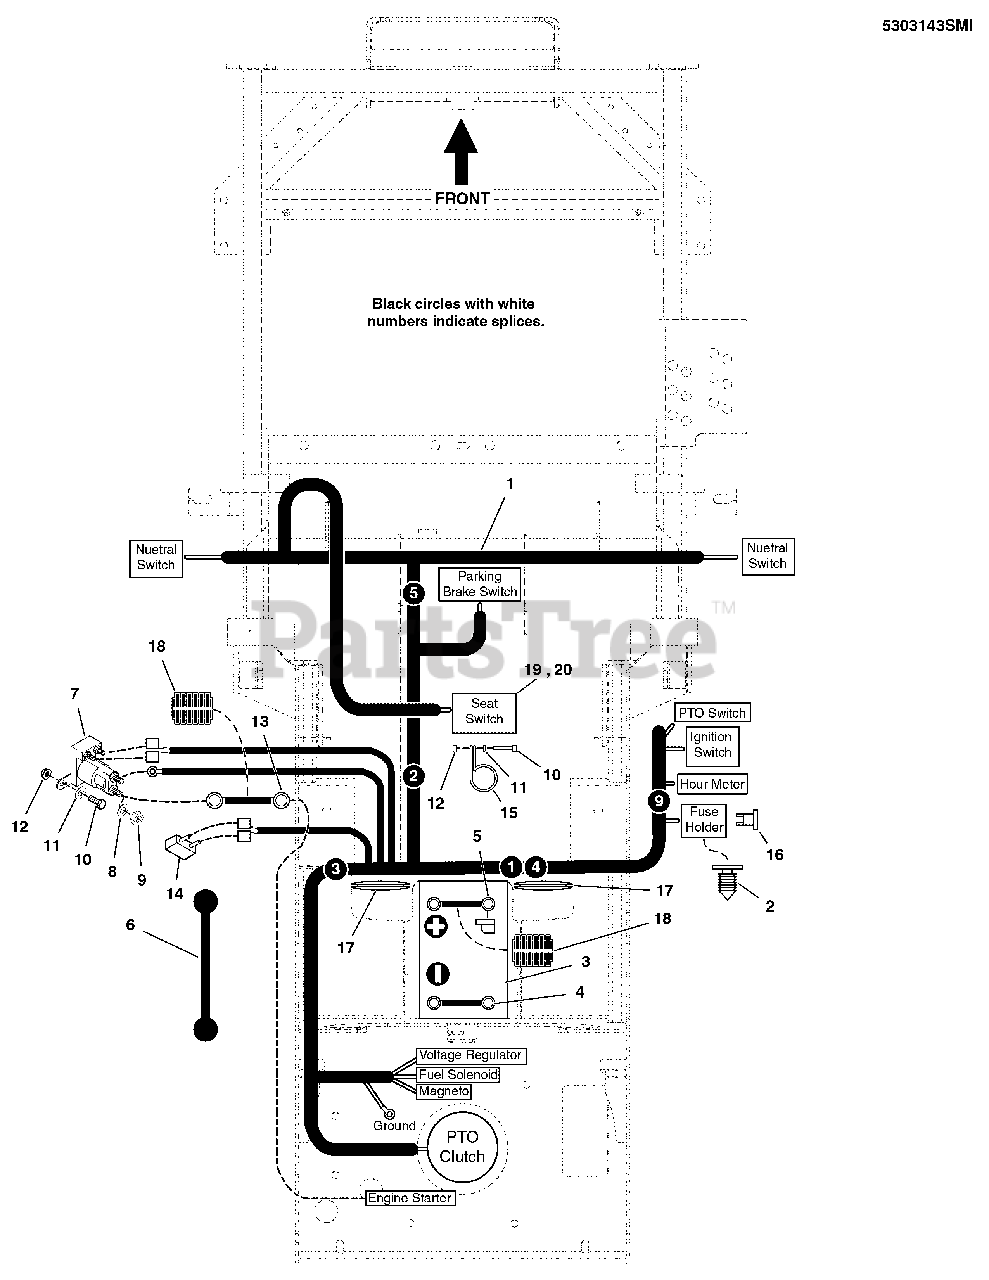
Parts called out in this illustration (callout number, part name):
1	WIRE HARNESS, C TURF,WARNER, IS600/IS700
2	FIR TREE MOUNT, PACKARD
3	BATTERY, WET (BCIU1, 340 CCA)
4	BATTERY CABLE, NEGATIVE, 14
5	BATTERY CABLE, POSITIVE, 22
6	STRAP-BLACK RUBB
7	SOLENOID-4 POLE 12 VOLT DC (TROMBETTA)
8	WASHER, 5/16 LIGHT LOCK
9	NUT, 5/16-24 JAM
10	BOLT, 1/4-20 X 3/4 GD5 YZ
11	WASHER, 1/4 SAE (5025154)
12	NUT, 1/4-20 HEX SERR. FLANGE
13	BATTERY CABLE, POSITIVE, 22
14	BREAKER-CIRCUIT 12VOLT 20AMPS W/TAB
15	CLAMP, VINYL INSULATED
16	FUSE, ATO 15 AMP
17	GROMMET, 2" ID
18	WIRE LOOM, 3/8 ID X 18 IN
19	SEAT SWITCH, MILSCO, TWIST-IN
20	SEAT SWITCH, MILSCO, BOLT-IN
21	TIE, SELF-LOCKING, 6"
